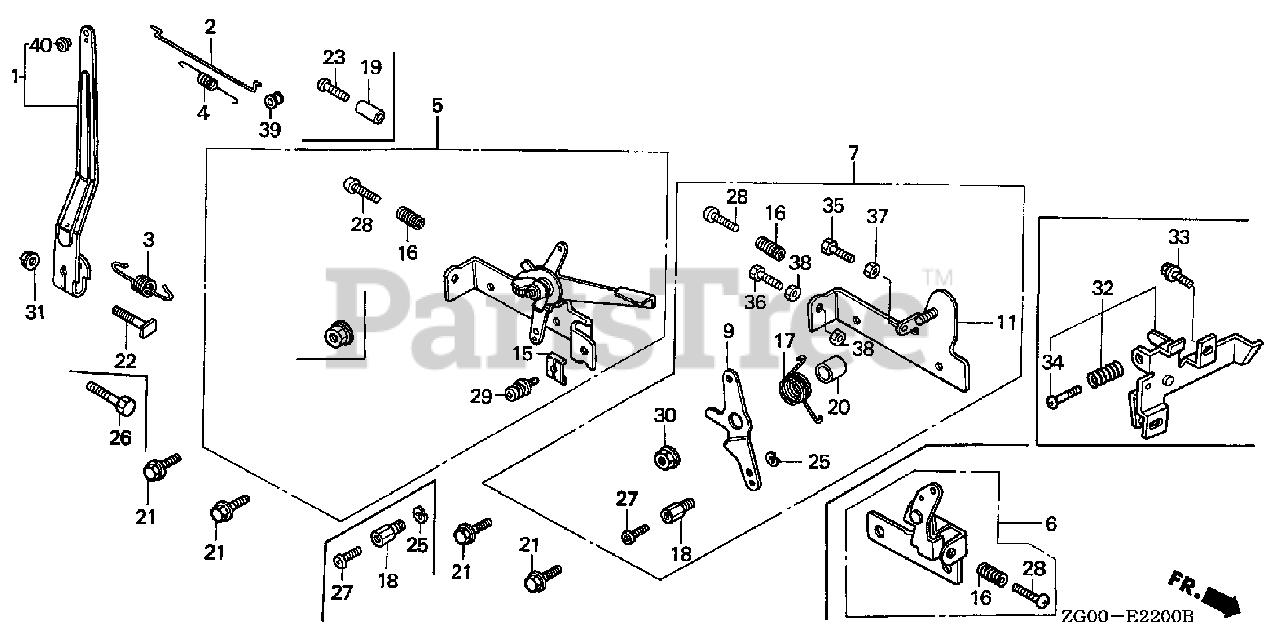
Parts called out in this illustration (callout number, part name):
1	ARM, GOVERNOR
2	ROD, GOVERNOR
3	SPRING, GOVERNOR
4	SPRING, THROTTLE RETURN
5	CONTROL ASSY. (STD)
15	HOLDER, CABLE
16	SPRING, CONTROL ADJUSTING
21	BOLT, FLANGE (6X12) (CT200)
22	BOLT, GOVERNOR ARM
25	CIRCLIP (5MM)
27	SCREW, PAN (4X8)
28	SCREW, PAN (5X25)
29	SCREW, PAN (5X16)
31	NUT, FLANGE (6MM)
